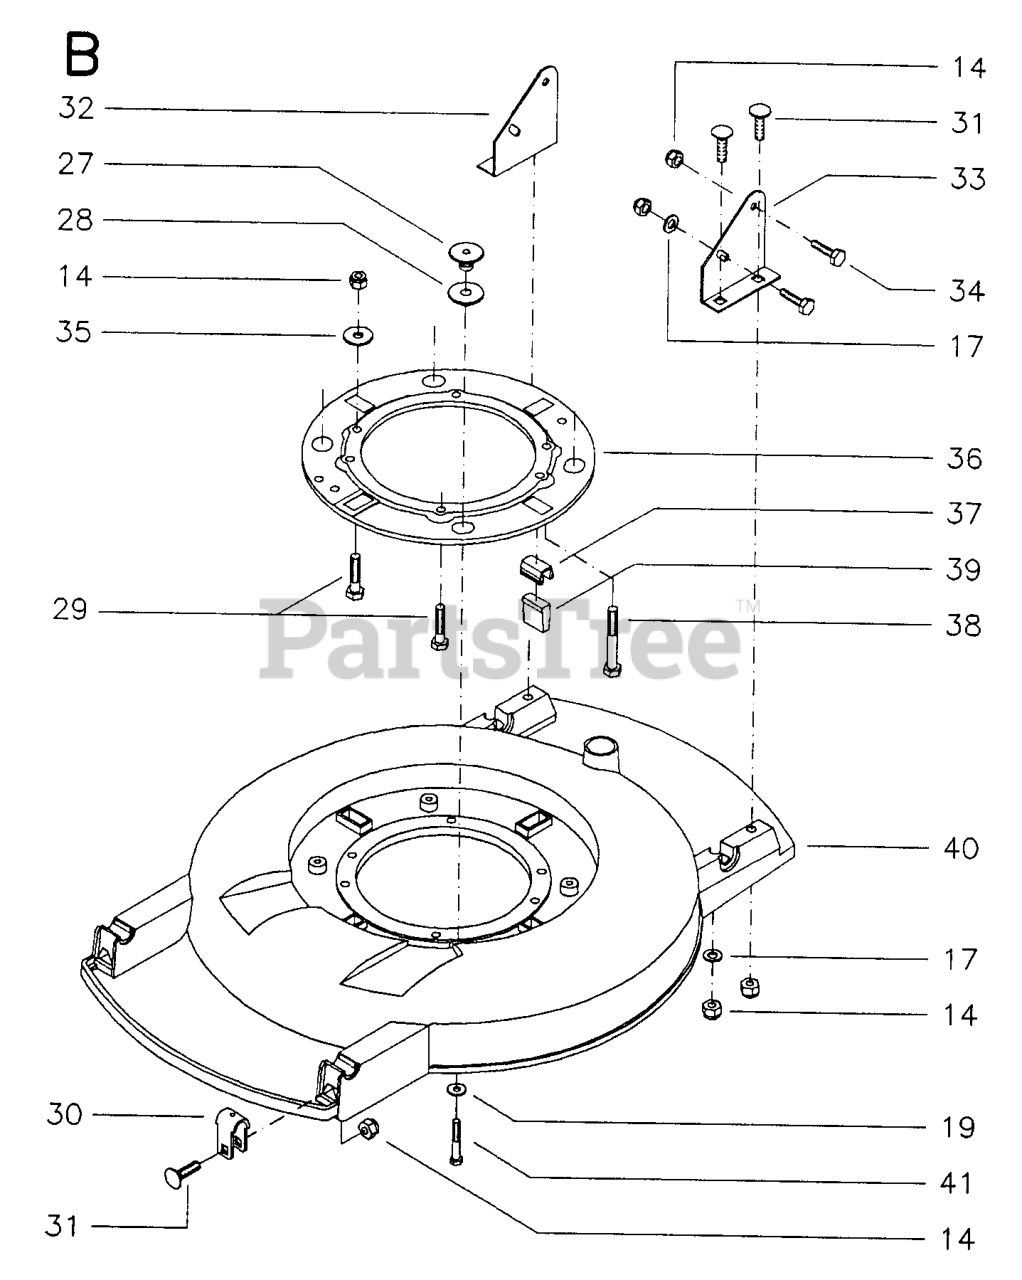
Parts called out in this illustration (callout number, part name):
14	LOCKNUT M8
17	WASHER - 15X7.3X1.6
30	BEARING HOLDER
32	HANDLE BRACKET
33	HANDLE BRACKET
34	BOLT - M8X16
